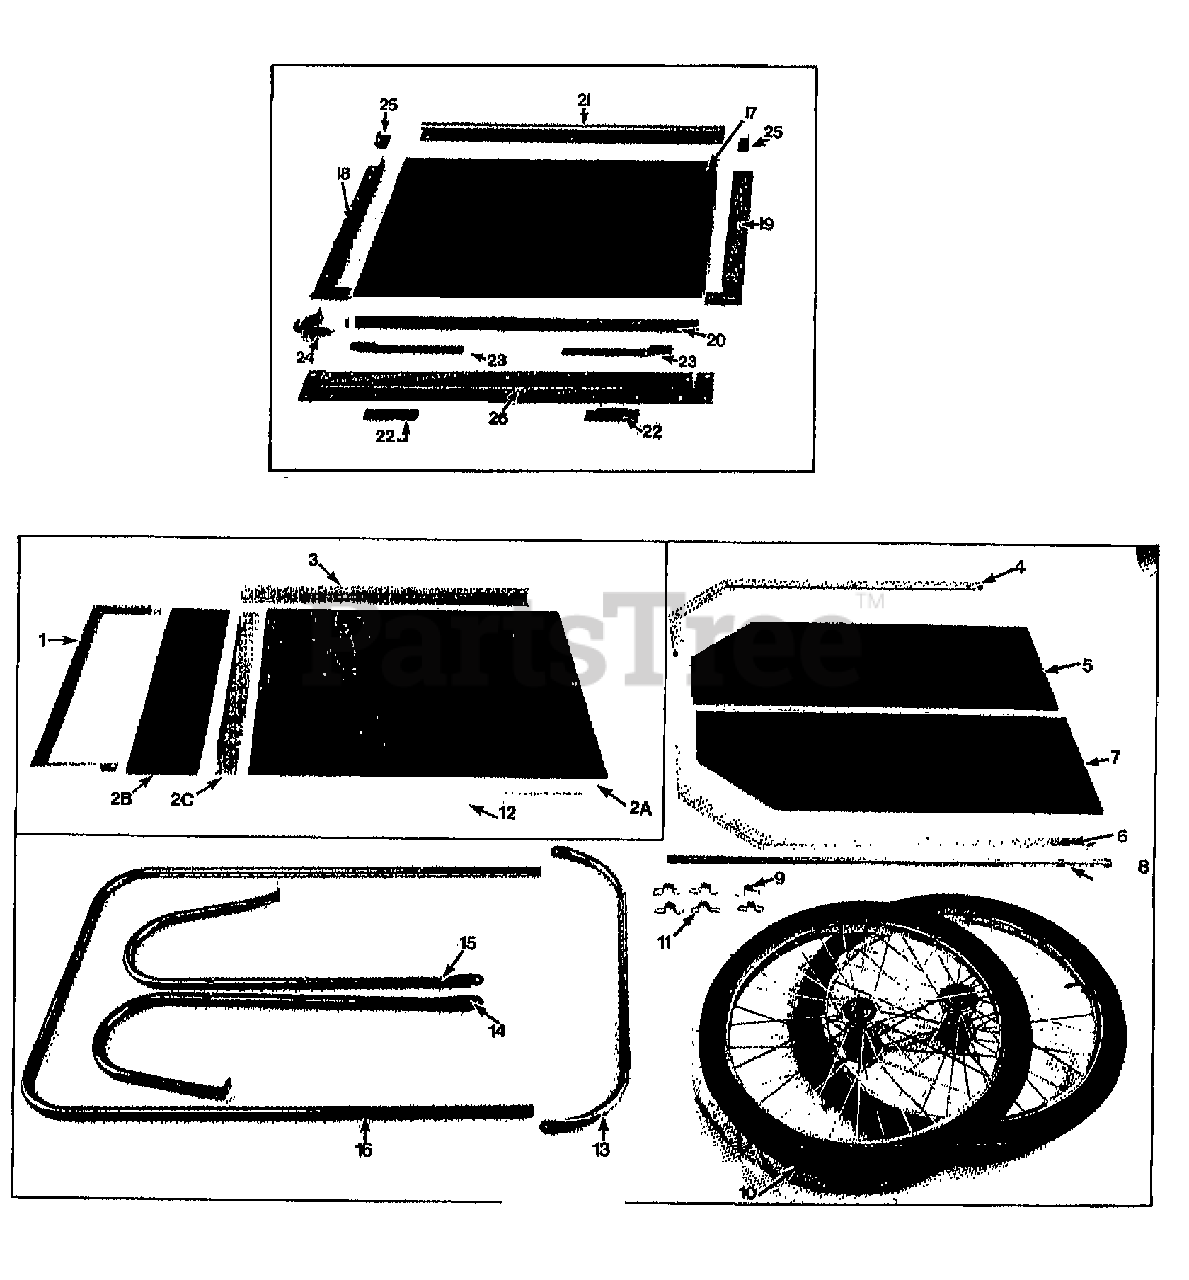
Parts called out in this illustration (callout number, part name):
1	PROTECTOR-M26 REAR EDGE
2A	PANEL-BOTTOM FRT W/TNUTS
2B	PANEL-REAR BOTTOM W/TNUTS
2C	SUPT-REAR BOTTOM KM26
3	ANGLE-26 SOLID FRONT BOT LT
4	PROTECTOR-SIDE LT
5	PANEL-03052 LFT KM26 W/NUTS
6	PROTECTOR-26 TOP EDGE RT
7	PANEL-RT W/TNUTS KM26
8	AXLE-MODEL 26
9	CLAMP-AXLE 20 & 26
10	WHEEL&TIRE-COMP. M26
10	TUBE-(ONLY) M26
10	TIRE (ONLY) M26 DIA TREAD
10	BEARINGS-WHEEL 20&26
11	WHEEL-RIM & BEARING
11	CLAMP-HANDLE KM26
12	ANGLE-BOTM 26 SOLID FRONT RT
14	BRACE-CROSS KM26
15	STAND-RIGHT HAND KM26
16	STAND-LEFT HAND KM26
16	HANDLE-KM26
17	PANEL-FRNT DOOR W/T NUTS
18	SUPT-SIDE 26 SWING FRONT LT
19	SUPT-SIDE 26 SWING FRONT RT
20	EDGE-BOT 26 SWING FRONT
21	EDGE-TOP 26 SWING FRONT
22	PLATE-LATCH 20&26 SWING FRONT
23	LATCH-20&26 SWING FRONT
24	ASSM-20&26 PLUNGER
25	HINGE-20&26 SWING FRONT
26	SUPT-BOT 26 SWING FRONT
